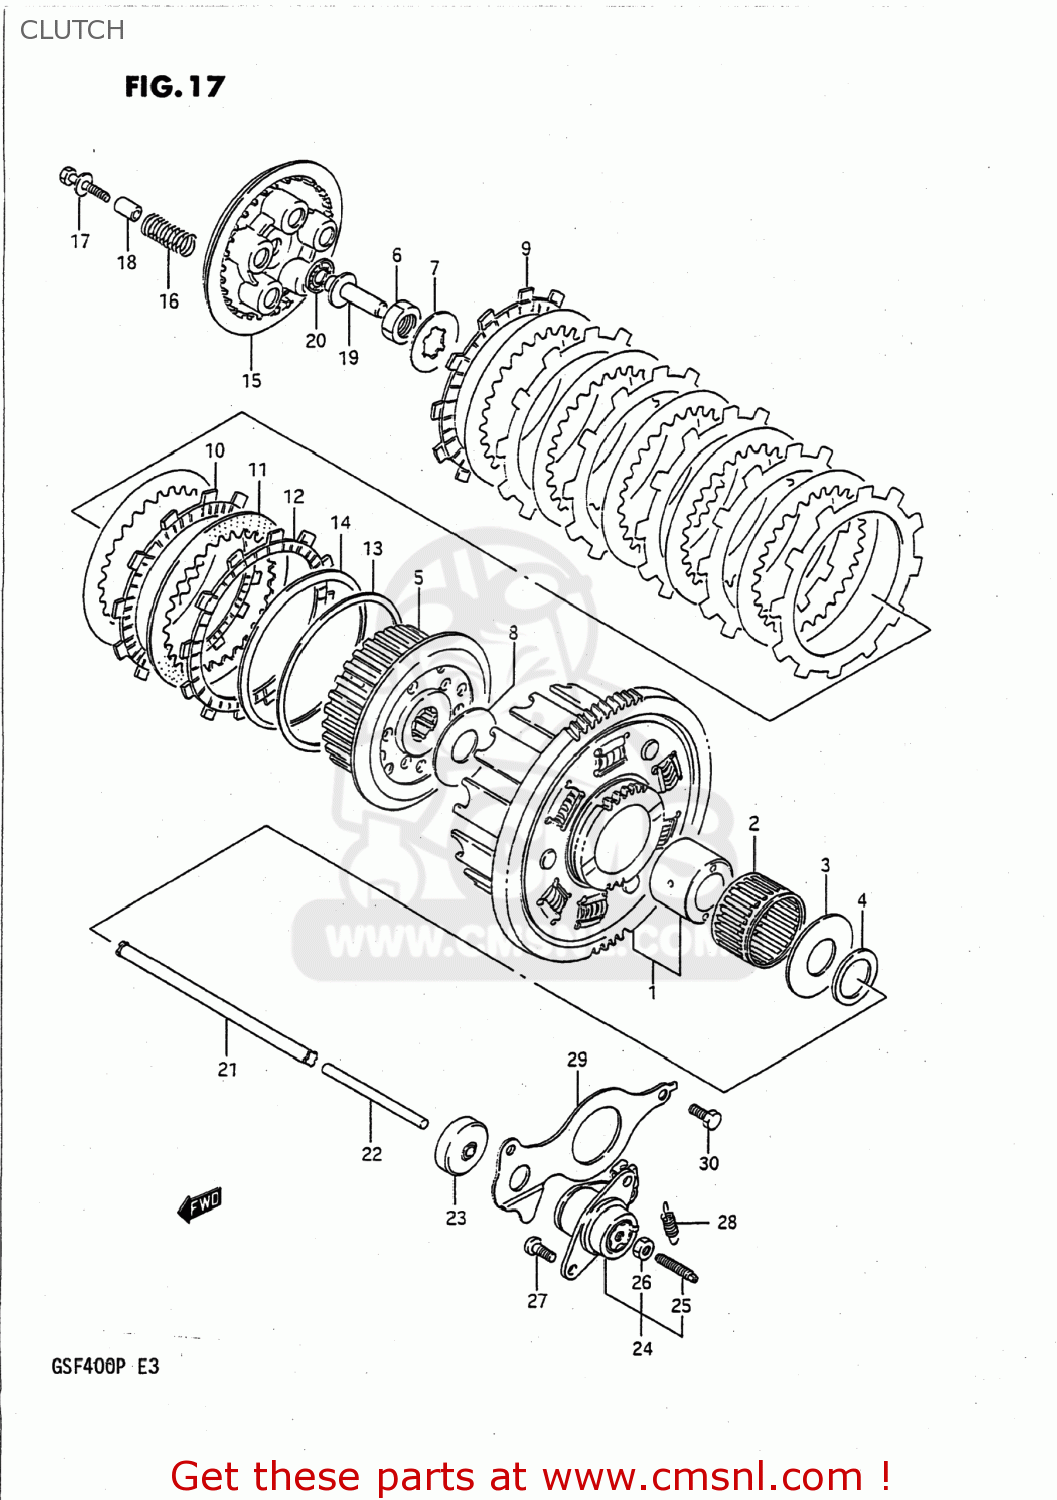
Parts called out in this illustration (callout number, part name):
1	GEAR ASSEMBLY,PRIMARY DRIVE
2	BEARING(37X42X27)
3	WASHER,22X50X2.5
4	WASHER(22X32X3)
5	HUB,CLUTCH SLEEVE
6	NUT
7	WASHER,LOCK
8	WASHER(20X50X2)
9	PLATE,CLUTCH DRIVE (NAS)
10	PLATE,CLUTCH DRIVE (NAS)
11	PLATE,CLUTCH DRIVEN (NAS)
12	PLATE,CLUTCH DRIVE (NAS)
13	SEAT,WAVE WASHER
14	WASHER
15	DISC,CLUTCH PRESSURE
16	SPRING
17	BOLT(5X40)
18	SPACER (5.5X9.5X22)
19	PIECE,CLUTCH PUSH
20	BEARING(10X22X2.8)
21	ROD,CLUTCH PUSH
22	ROD,CLUTCH PUSH,L
23	SEAL,OIL(6X34X7.5)
24	SCREW ASSY,CLUTCH RELEASE
25	SCREW(6X25)
26	NUT 6MM
27	SCREW 6X12
28	SPRING
29	PLATE,CLUTCH PUSH ROD
30	BOLT
